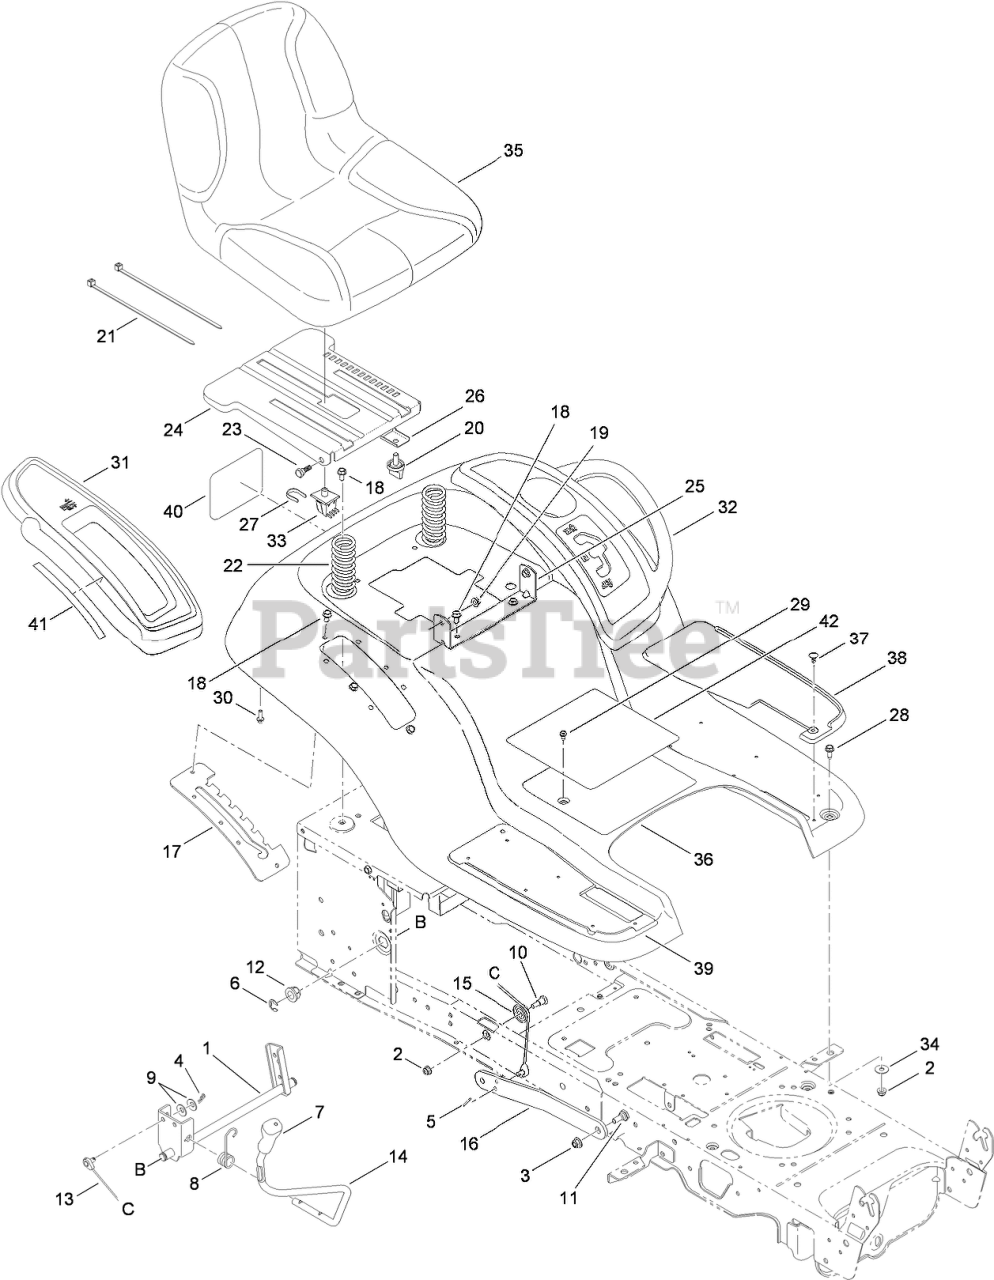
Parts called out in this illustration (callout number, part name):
1	LIFT SHAFT ASM
2	NUT-LOCK, FLANGE
3	NUT-LOCK, FLANGE
4	PIN-COTTER
5	PIN-COTTER
6	RING-E
7	GRIP-HANDLE
8	SPRING-TORSION
9	WASHER-SPRING
10	BOLT-SHOULDER
11	BOLT-SHOULDER
12	BEARING-FLANGE
13	CABLE-LIFT
14	HANDLE-LIFT
15	PULLEY-CABLE
16	ARM-LIFT
17	BRACKET-LIFT
18	SCREW-TAP
19	NUT-LOCK, FLANGE
21	TIE-CABLE
22	SPRING-COMPRESSION
23	BOLT-SHOULDER
24	BRACKET-MOUNT, SEAT
25	BRACKET-PIVOT, SEAT
26	BRACKET-KNOB, ADJUSTMENT
27	CLIP-RETENSION
28	SCREW-HH
29	SCREW-HWHTF
30	SCREW-TAP
31	COVER-FENDER, RH
32	COVER-FENDER, LH (W/CUPHOLDER)
33	SWITCH-SEAT
34	WASHER-FLAT
35	SEAT-HIGH
36	FENDER
37	CLIP-RATCHET
38	PAD-FOOT, LH
39	PAD-FOOT, RH
40	DECAL-TORO
41	DECAL-HOC
42	DECAL-SAFETY
